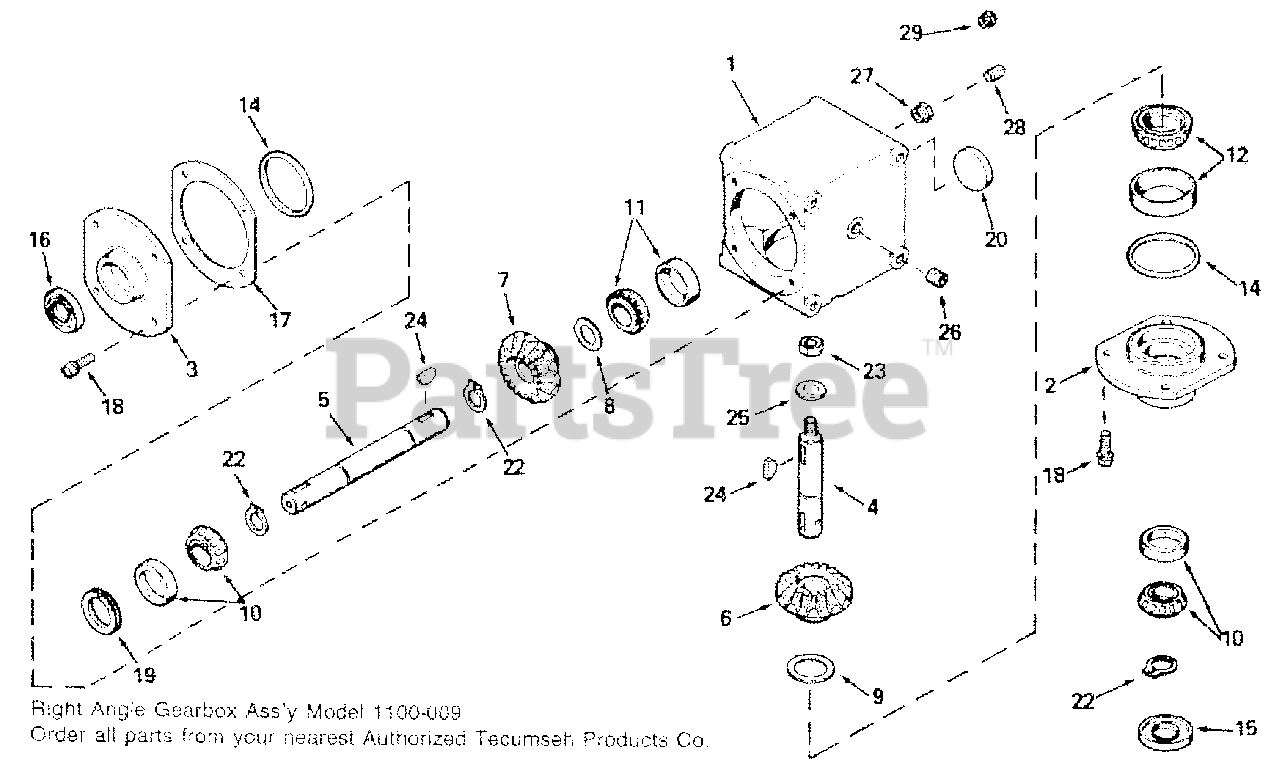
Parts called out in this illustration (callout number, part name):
1	Housing, Right angle drive
2	Cap, Retainer
3	Cap, Retainer
4	Shaft, Output
5	Shaft, Input
6	Gear, Bevel (20 teeth)
7	Gear, Bevel (27 teeth)
8	Shim (1-1/2" O.D. x 1-1/64" I.D. x .002 thick)
9	Shim (2.000" O.D. x 1.531" I.D. x .002 thick)
10	Bearing & Cup Ass'y.
11	Bearing & Cup Ass'y.
12	Bearing & Cup Ass'y
14	"O" Ring
15	Seat, Oil
16	Seal, tail
17	Shim, Cap retainer
18	Screw, Hex Hd Sems, 5/16-18 x 1
19	Ring, Load
22	Ring, Retaining
23	Jam Nut, 3/4-16
24	Key, Woodruff
25	Washer, Flat
26	Plug, Pipe, 1/4-18
27	Reducer, Pipe (1/4-18 to 1/8-27)
28	Plug, Pipe
29	Valve, Relief
